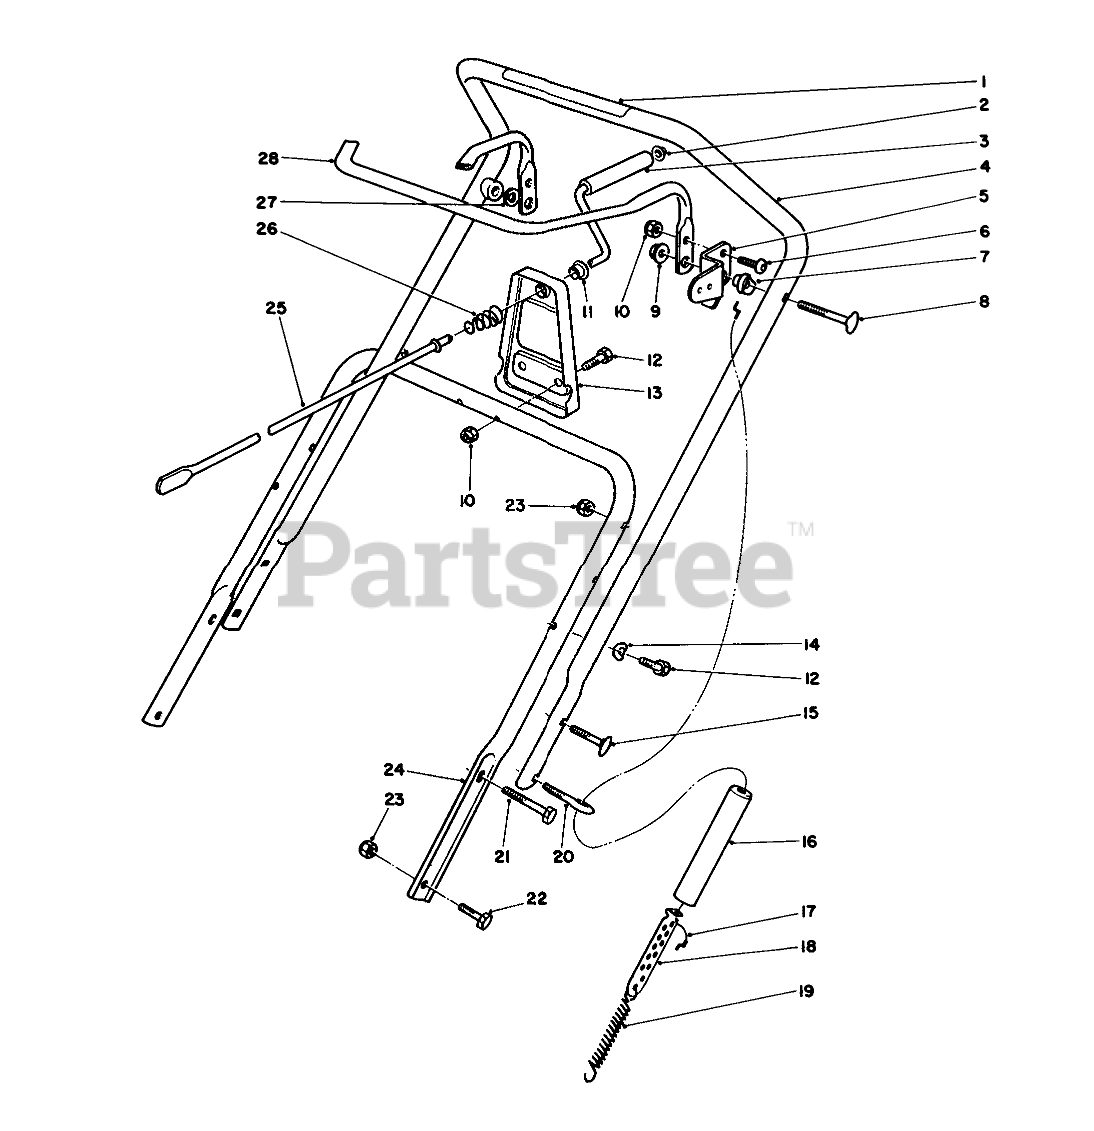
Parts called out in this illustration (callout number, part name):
1	Decal-Rotor Drive
2	RETAINER-PUSH ON
3	GRIP-CONTROL, CHUTE
4	Handle-Upper
5	Arm-Clutch Cable
6	SCREW-HSBH
7	SPACER-BAR, CONTROL
8	SCREW-HANDLE
9	NUT-LOCK, NI
10	NUT-LOCK, NI
11	Bushing
12	SCREW-HH
13	Support-Crank
14	WASHER
15	SCREW
16	COVER-SPRING
17	CLUTCH CABLE
18	ADJUSTER-CABLE
19	SPRING-EXTENSION
20	BOLT-EYE
21	SCREW-HH
22	SCREW-HH
23	NUT-LOCK, NI
24	LOWER HANDLE
25	ROD-CRANK, CHUTE
26	SPRING-COMPRESSION
27	WASHER
28	Bar-Control
